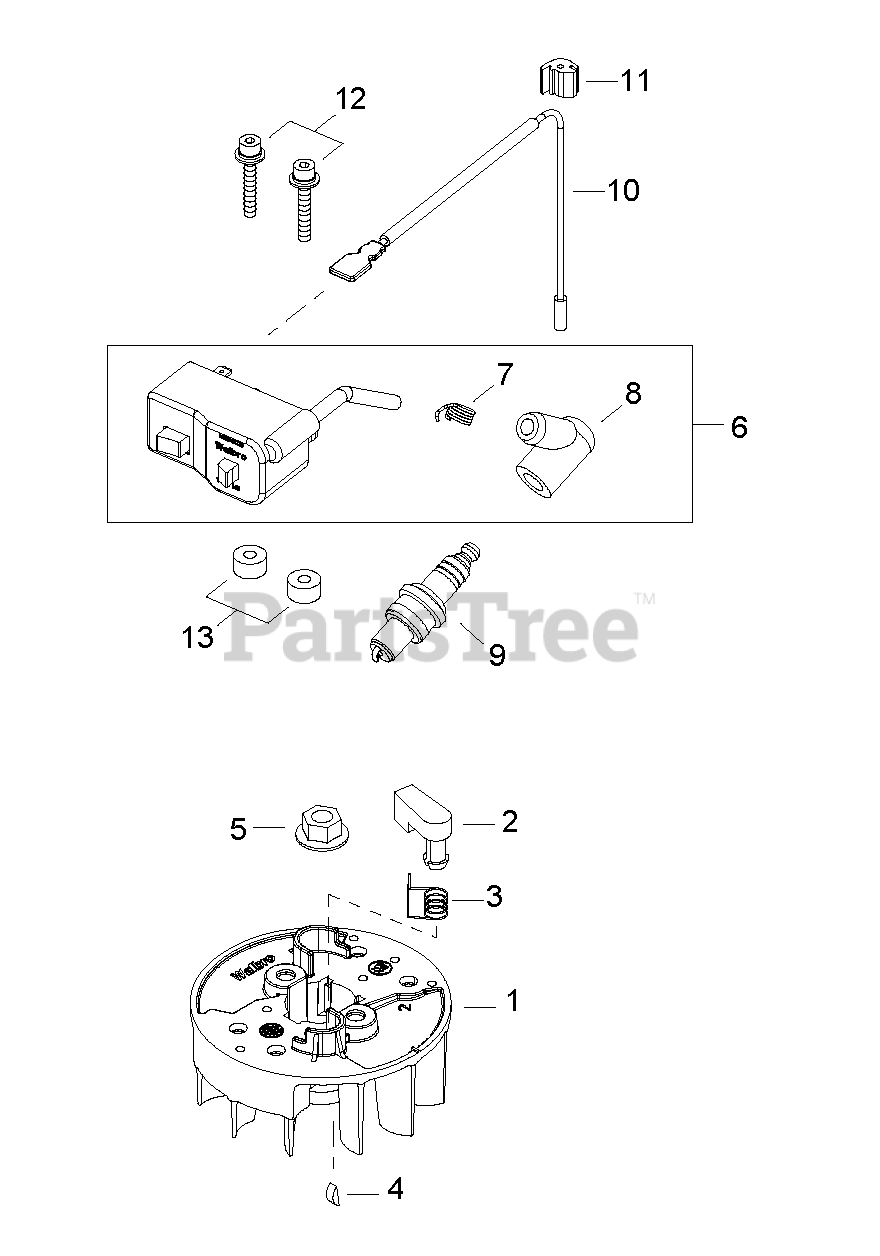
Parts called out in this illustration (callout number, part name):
1	FLYWHEEL
2	PAWL
3	SPRING, TORSION
4	KEY, WOODRUFF 3×10
5	NUT M8
6	COIL ASSY, IGNITION
7	TERMINAL, SPARK PLUG
8	CAP, SPARK PLUG
9	SPARK PLUG - NGK
10	LEAD - IGNITION
11	GROMMET, LEAD
12	BOLT M4×26
13	INSULATOR 4.2×11×6
